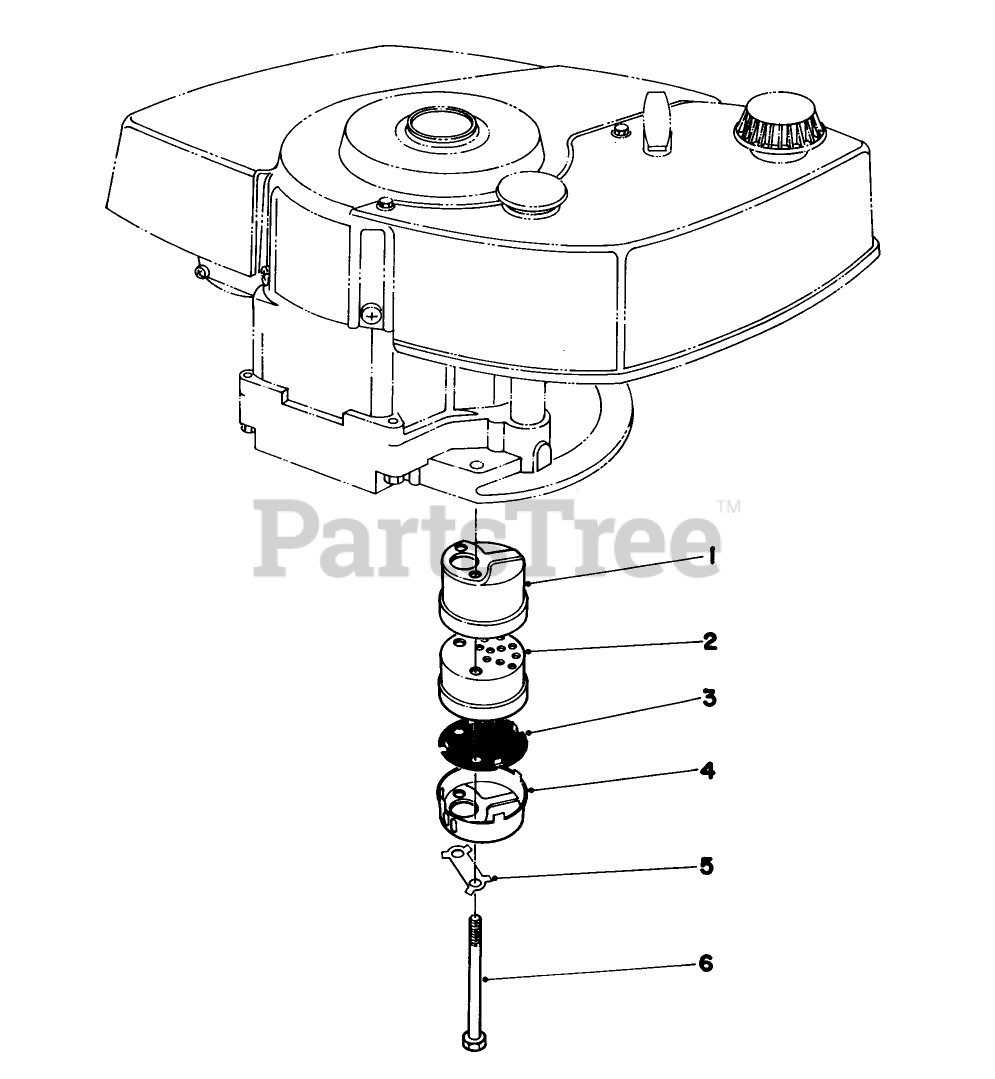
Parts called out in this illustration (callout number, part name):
1	Muffler Housing
2	Baffle Muffler
3	Screen Spark Arrester
4	Muffler Cap-Arrester
5	CLIP - LOCKING
6	SCREW-HH
